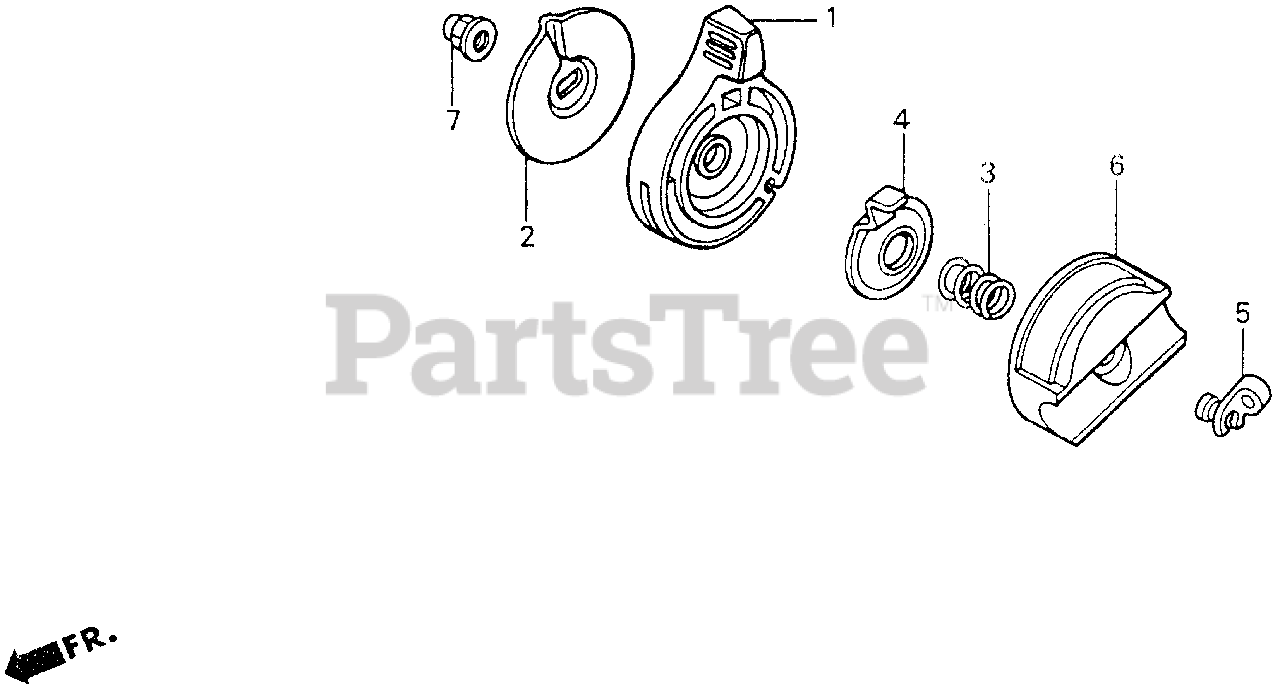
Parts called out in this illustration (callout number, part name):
1	LEVER, THROTTLE
2	PLATE, THROTTLE LEVER
3	SPRING, THROTTLE LEVER
4	SEAT, SPRING
5	BAND B1, CABLE
6	COVER, CONTROL
7	NUT, CAP (6MM)
